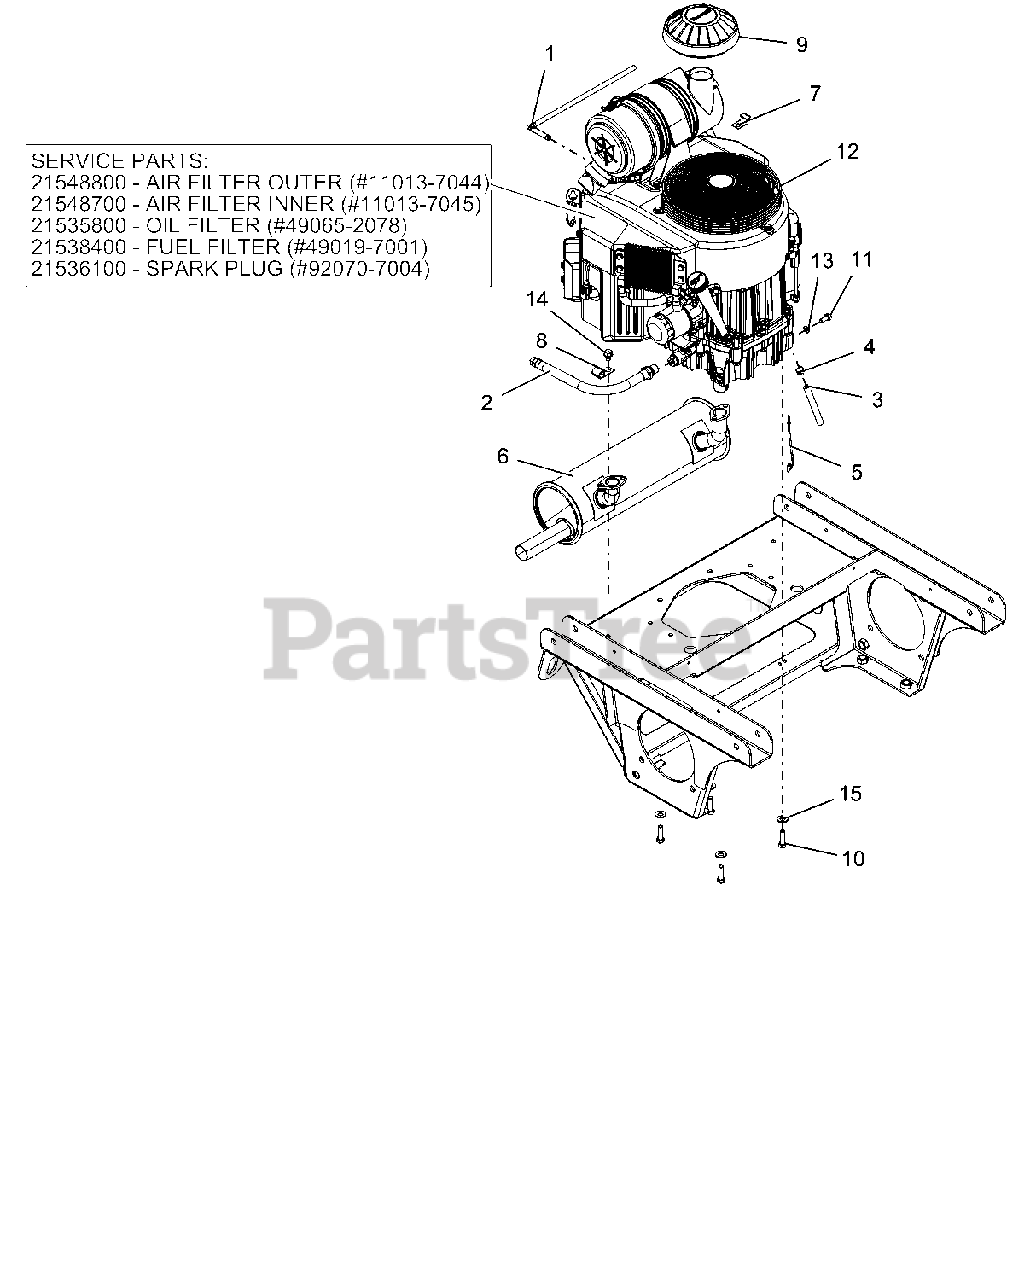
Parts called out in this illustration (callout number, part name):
1	ASM, KAWASAKI VAPOR LINE
1	AIR FILTER OUTER )#11013-7044)
1	AIR FILTER INNER (#11013-7045)
1	OIL FILTER (#49065-2078)
1	FUEL FILTER (49019-7001)
1	SPARK PLUG (#92070-7004)
2	HOSE, OIL DRAIN
3	.25 LOW-PERM GAS HOSE 16.00" LG - VALVE TO ENGINE
4	CLAMP, FUEL LINE
5	LEAD - STARTER SOLENOID
6	MUFFLER, 27-31 FX KAW
7	CLAMP, J
9	CAP, AIR CLEANER INTAKE (2")
10	BLT-HEX .38-16X1.25 GR5 YWZC NYTORQ
11	@BLT-HEX M8-1.25X20 YWZC
12	ENGINE, KAWASAKI FX850
13	WSHR-LK .31X.078 REG YWZC
14	SCR-TAP .38-16X.50 HWH TR YWZ
15	WSHR, 3/8" SPRING DISC
